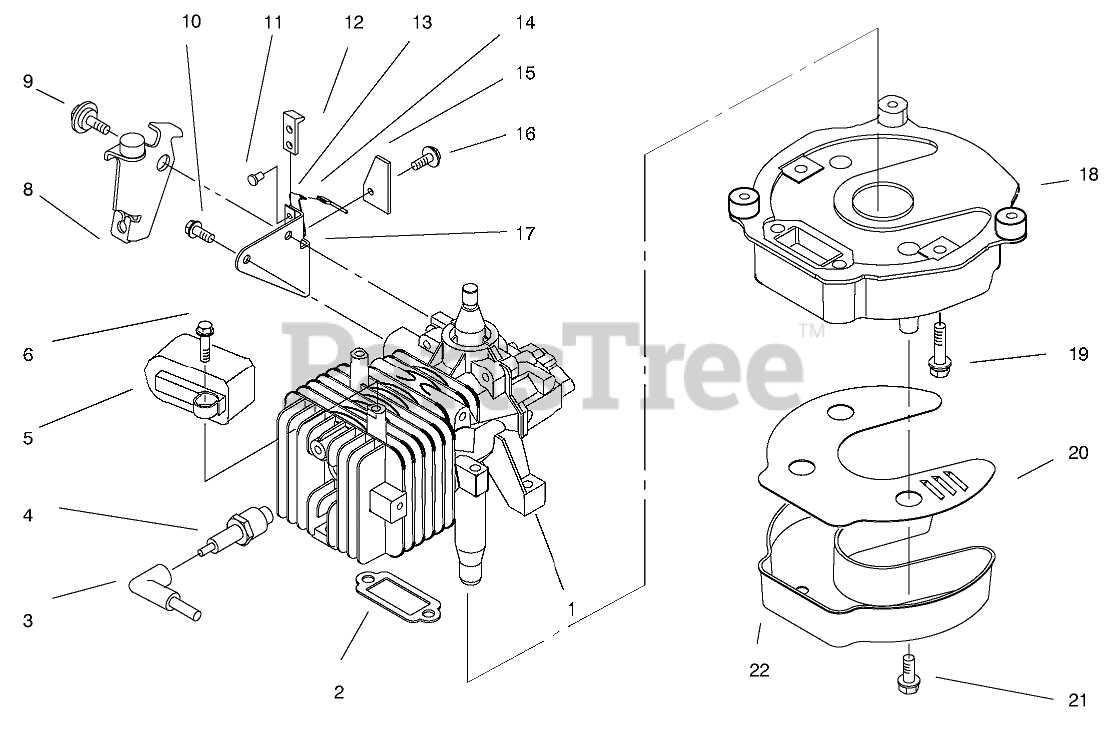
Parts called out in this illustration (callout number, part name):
1	Short Block (Incl. Ref. #2, Ref. #9 pg. 8)
2	GASKET-EXH. VF
3	CD Ignition
4	SPARK PLUG
5	CD Ignition (Incl. Ref. #3)
6	SCREW
8	PLATE-BRAKE
9	SCREW-SHOULDER
10	SCREW
11	RIVET-PLASTIC
12	STRAP-INSULATION
13	STRAP-GROUND
14	ELECTRICAL LEAD ASM
15	STOP-GROUND STRAP
16	SCREW
18	PLATE-MUFFLER V
19	SCREW V
20	BAFFLE-MUFFLER
21	SCREW
22	Cover-Muffler
